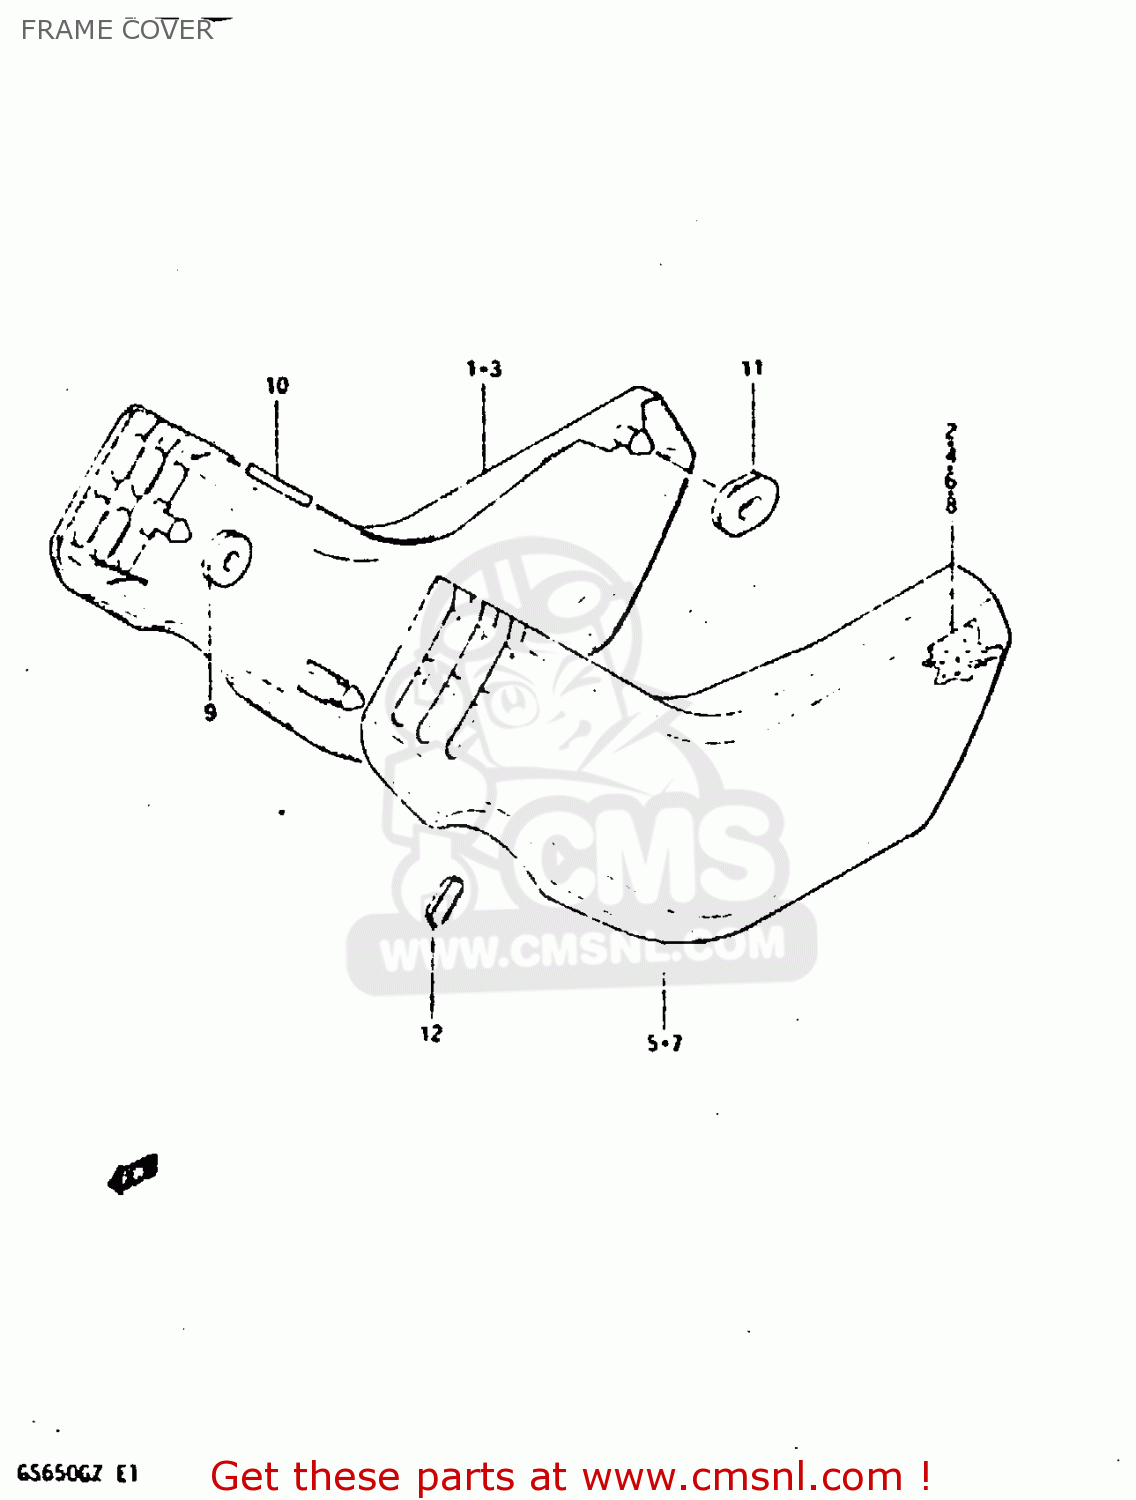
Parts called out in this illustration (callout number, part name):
1	COVER,FRAME,RIGHT
2	EMBLEM
3	COVER, FRAME RH (RED)
4	EMBLEM,FRAME COVER
5	COVER,FRAME,LEFT
6	EMBLEM
7	COVER, FRAME LH (RED)
8	EMBLEM,FRAME COVER
9	CUSHION
10	CUSHION
11	CUSHION
12	EMBLEM,FRAME COVER
